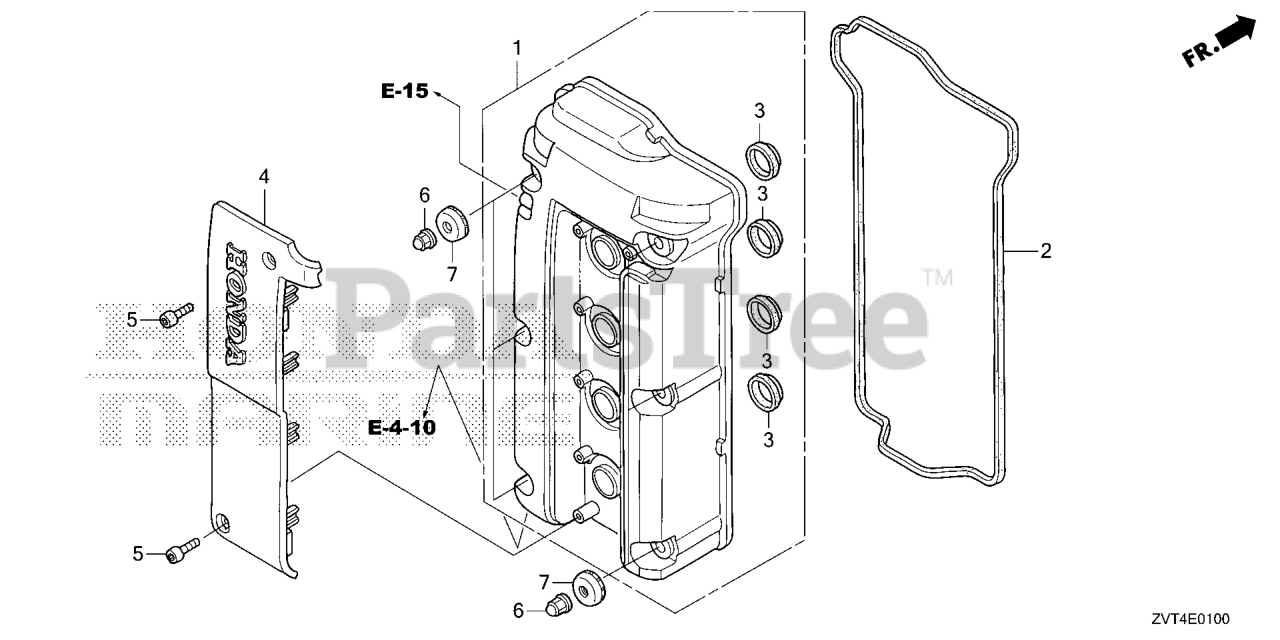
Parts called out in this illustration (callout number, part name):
1	COVER, CYLINDER HEAD *NH8* (DARK GRAY) (FOR 14540-RWC-A02)
2	GASKET, CYLINDER HEAD COVER
3	SEAL, SPARK PLUG TUBE (NOK)
4	COVER, PLUG HOLE COIL
5	BOLT, SOCKET (6X25)
7	WASHER, HEAD COVER
